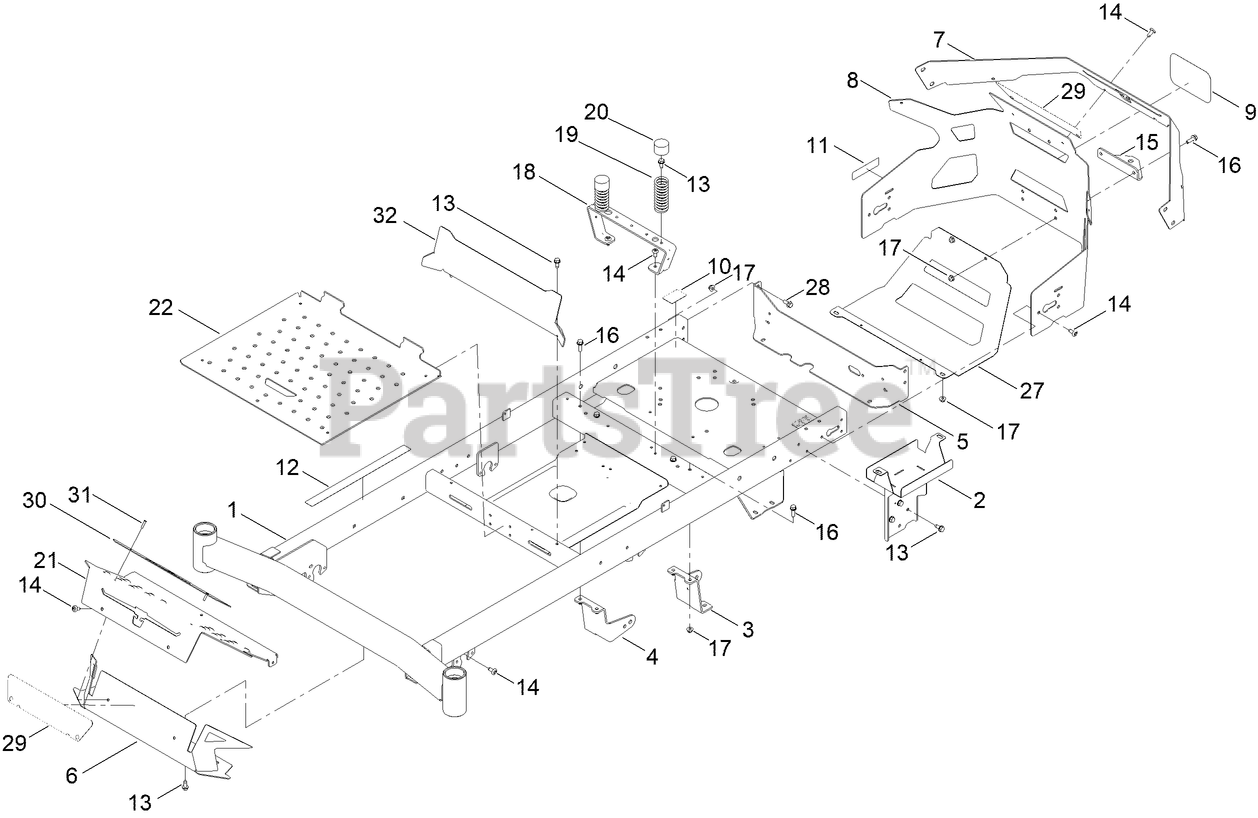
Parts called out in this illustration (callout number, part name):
1	SERVICE ASM-FRAME, TC
2	WA-BATTERY MOUNT
3	MOUNT-DRIVE, LH
4	MOUNT-DRIVE, RH
5	PLATE-MOUNT
6	FOOTREST-TOP
7	PLATE-REAR CLADDING TC
8	GUARD-ENGINE TC
10	DECAL-BYPASS
11	DECAL-SPARK ARRESTER
12	DECAL-WARNING
13	SCREW-HWHTF
15	BRACKET-HITCH
16	SCREW-HHF
17	NUT-HF
18	SUPPORT-SEAT
19	SPRING-COMPRESSION
20	CAP-PROTECTOR
21	PLATE-KICK
22	PAN-FLOOR
27	GUARD-MUFFLER [BLACK]
28	SCREW-HHF
29	DECAL-BACKER, RED
30	PLATE- TOEBOARD
31	RIVET-TRIFOLD
32	PLATE-KICK
